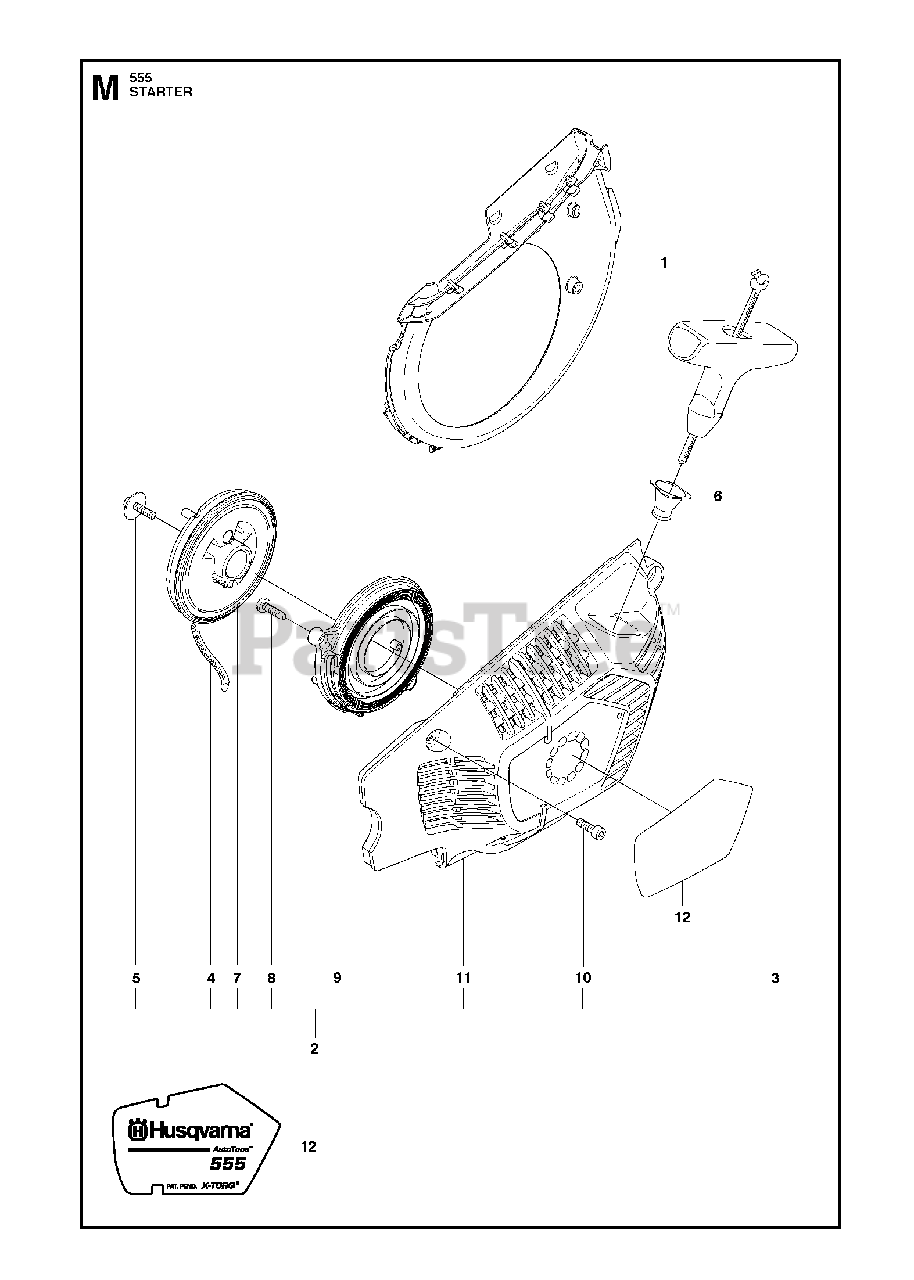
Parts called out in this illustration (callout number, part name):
1	COOLING AIR CONDUCTOR
2	RP STARTER ASSY
3	HANDLE
4	STARTER ROPE
5	SCREW
6	SLEEVE
8	SCREW
9	SPRING CASSETTE ASSY
10	SCREW
11	RP STARTER HOUSING
